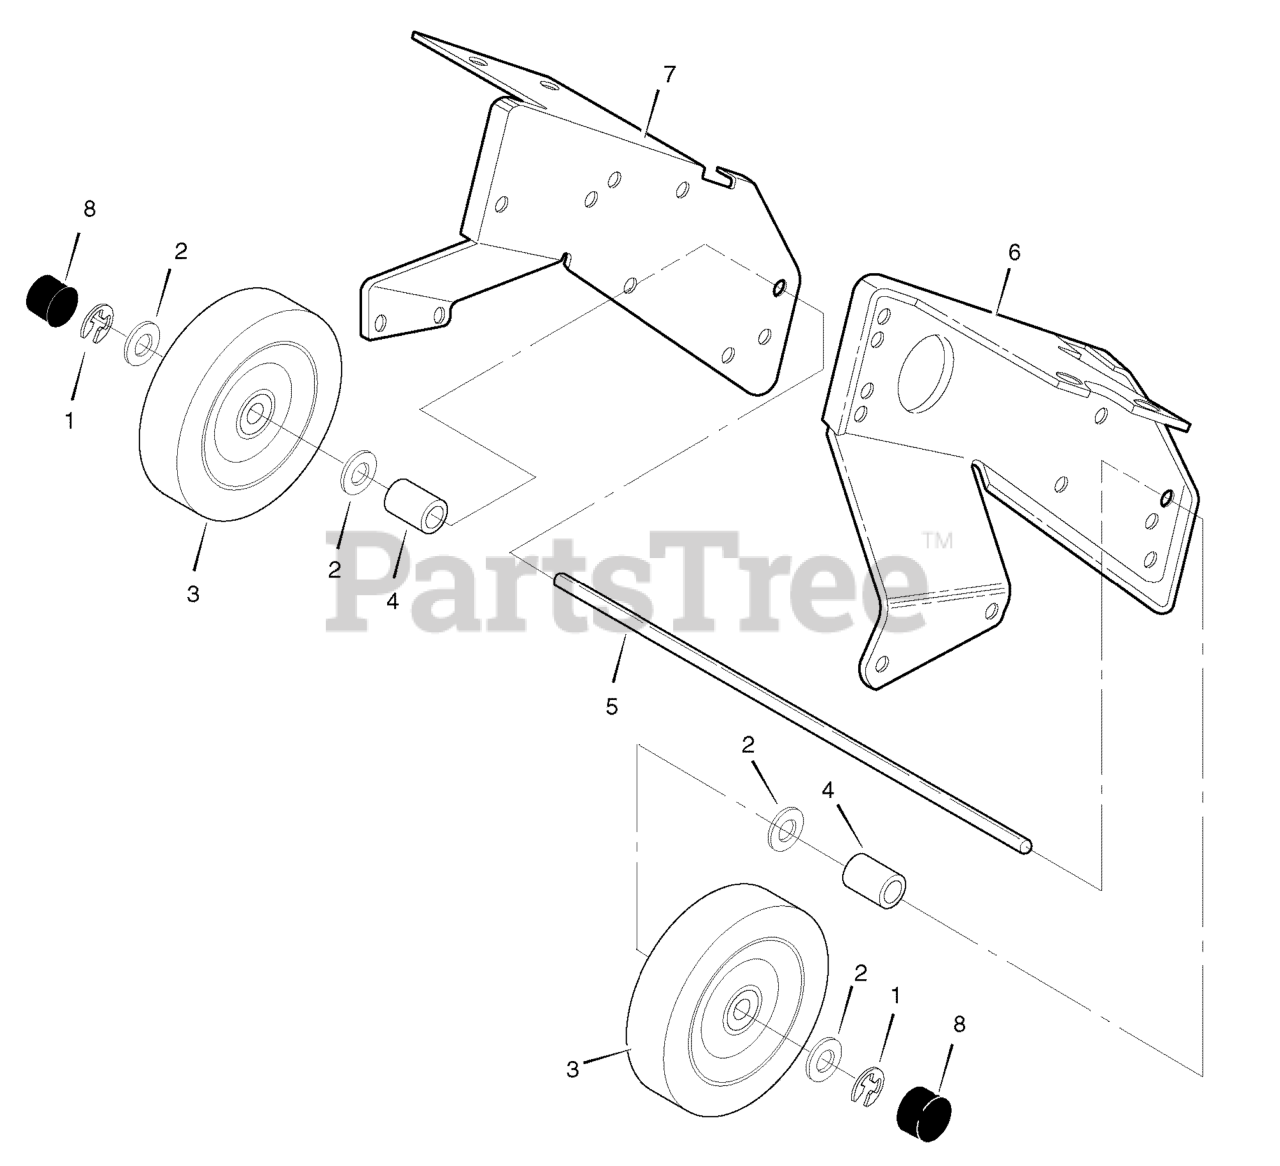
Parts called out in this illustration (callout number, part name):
1	RING, RET. E
2	WASHER, FLAT .406x.81x.07
3	7.75"X1.75" WHEEL
4	SPACER, SLEEVE
5	AXLE SHAFT
6	PLATE, REAR MT LH
7	PLATE, REAR MT RH
8	CAP, HUB
